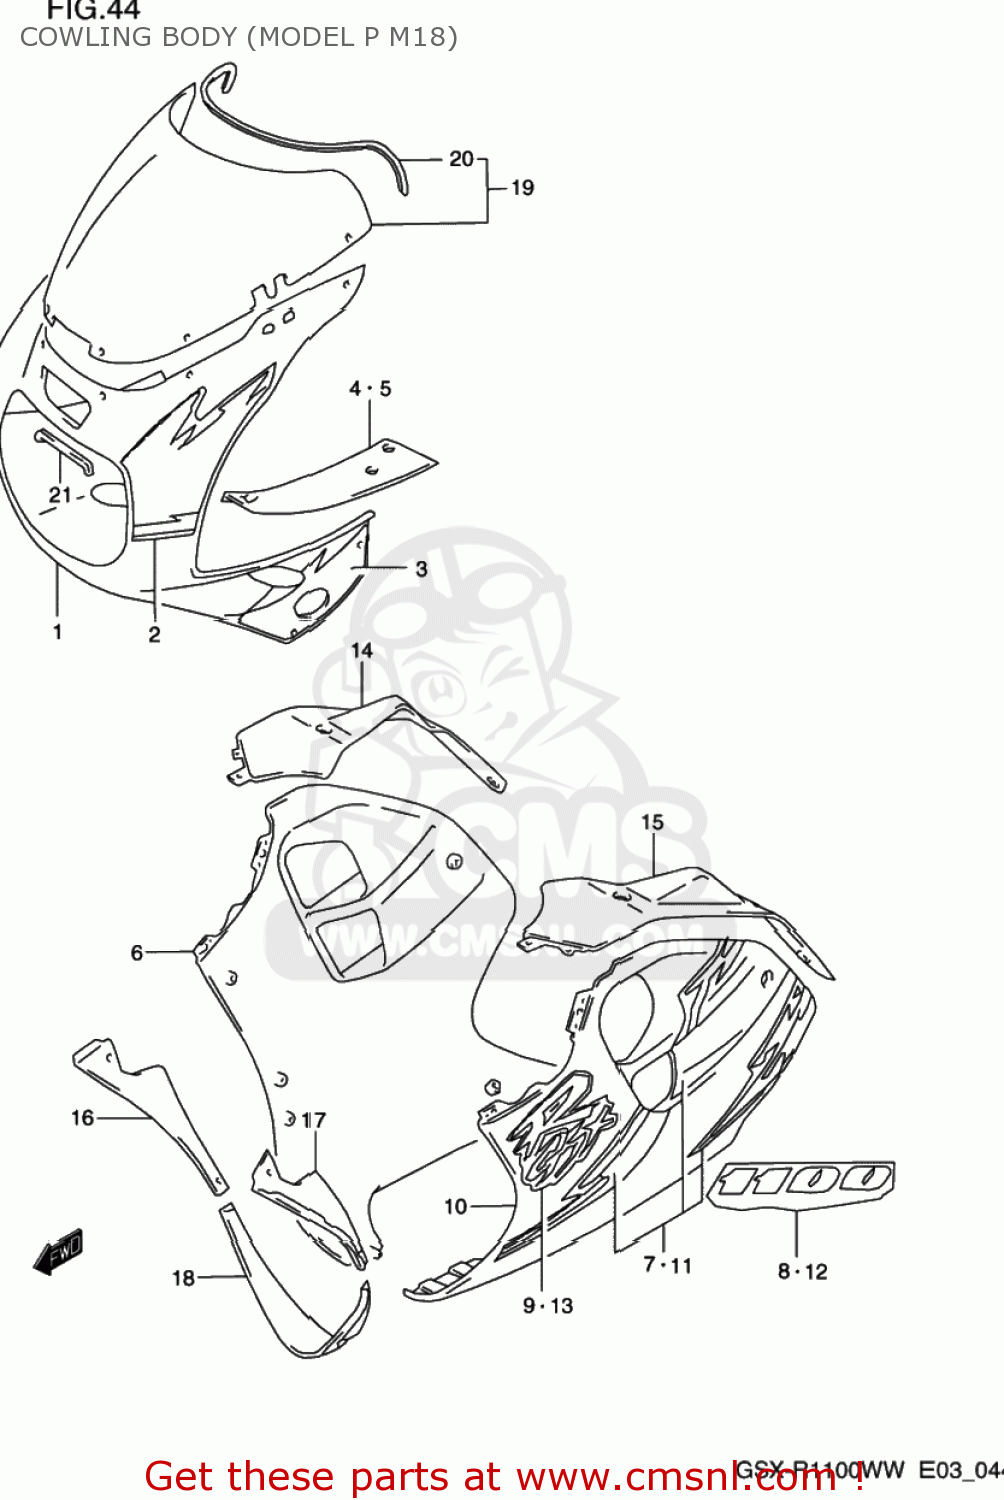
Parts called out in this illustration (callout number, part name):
1	COWLING ASSEMBLY,BODY
2	TAPE SET,COWLING BODY,FRONT
3	TAPE SET,COWLING BODY
4	PANEL,UPR,R
5	PANEL,UPR,L
6	COWLING ASSEMBLY,UNDER,RIGHT
7	TAPE SET,COWL UNDER,R
8	EMBLEM,COWLING UNDER,1100
9	EMBLEM,COWLING UNDER
10	COWLING ASSEMBLY,UNDER,LEFT
11	TAPE SET,COWL UNDER,L
12	EMBLEM,COWLING UNDER,1100
13	EMBLEM,COWLING UNDER
14	PANEL,LWR,R
15	PANEL,LWR,L
16	COWLING,UNDER INNER,R
17	COWLING,UNDER INNER,L
18	COWLING,UNDER CTR
19	SCREEN SET,WIND
20	MOLDING,WINDSCREEN
21	CUSHION,FR POSITION LAMP
